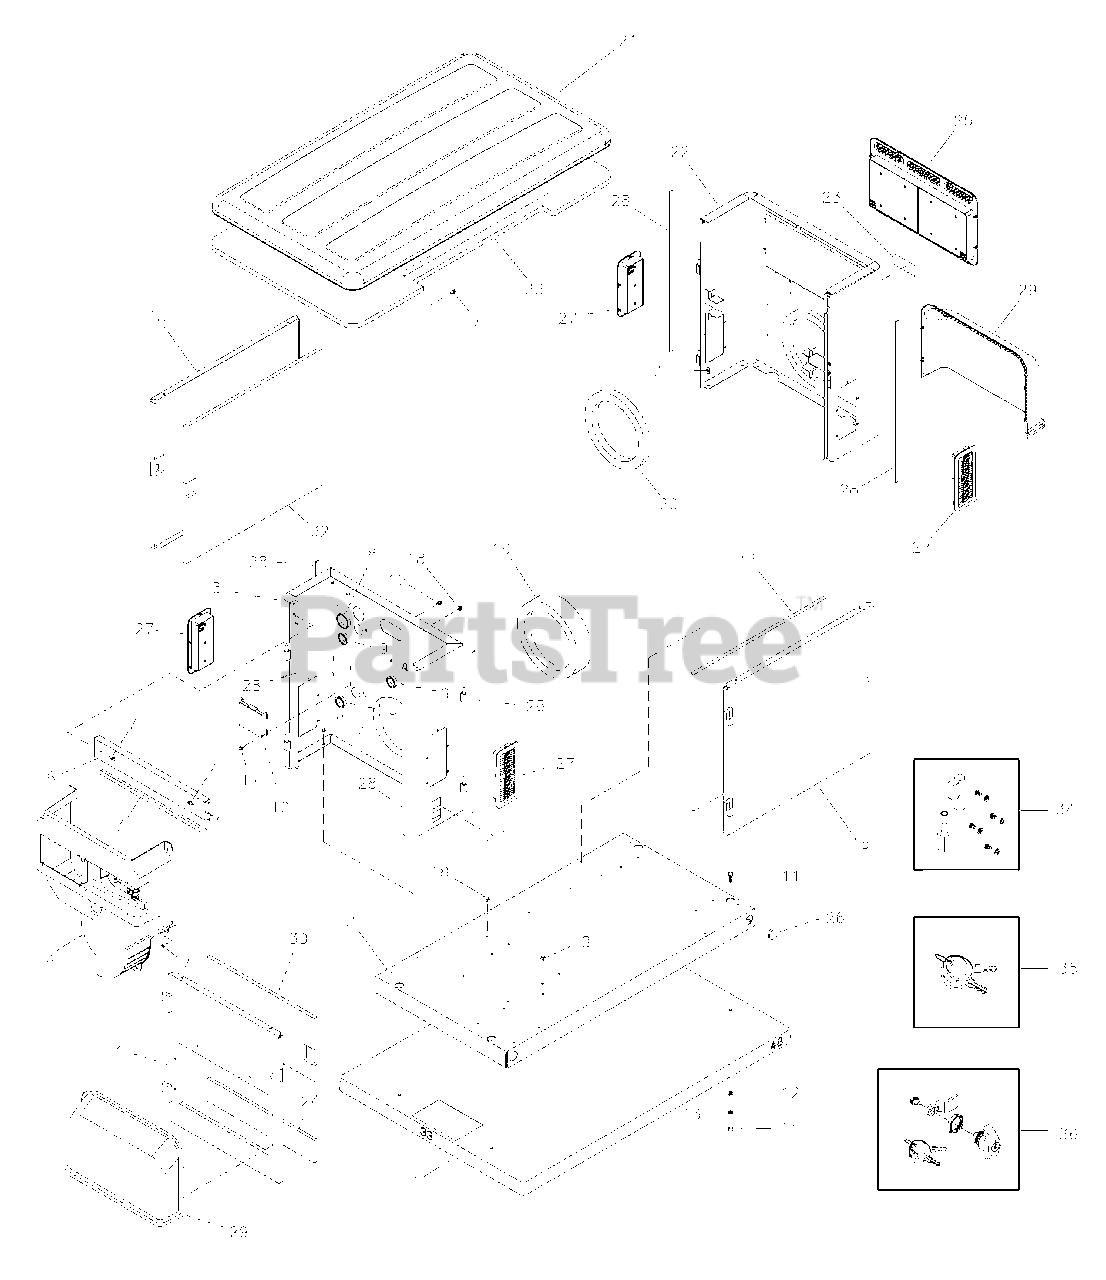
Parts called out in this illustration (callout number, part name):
1	PAD, Mounting w/ Holes
2	BASE
3	BULKHEAD, Engine
7	BOLT
10	REGULATOR, Voltage
11	*CAPSCREW, Hex Head, 3/8-16 x 1
12	WASHER, Flat, 3/8-M10
13	WASHER, Lock, 3/8
16	SEAL, Foam
18	MOUNT, Tie Wrap
20	SEAL, Foam
22	BULKHEAD, Alternator
29	COVER, Air Intake
